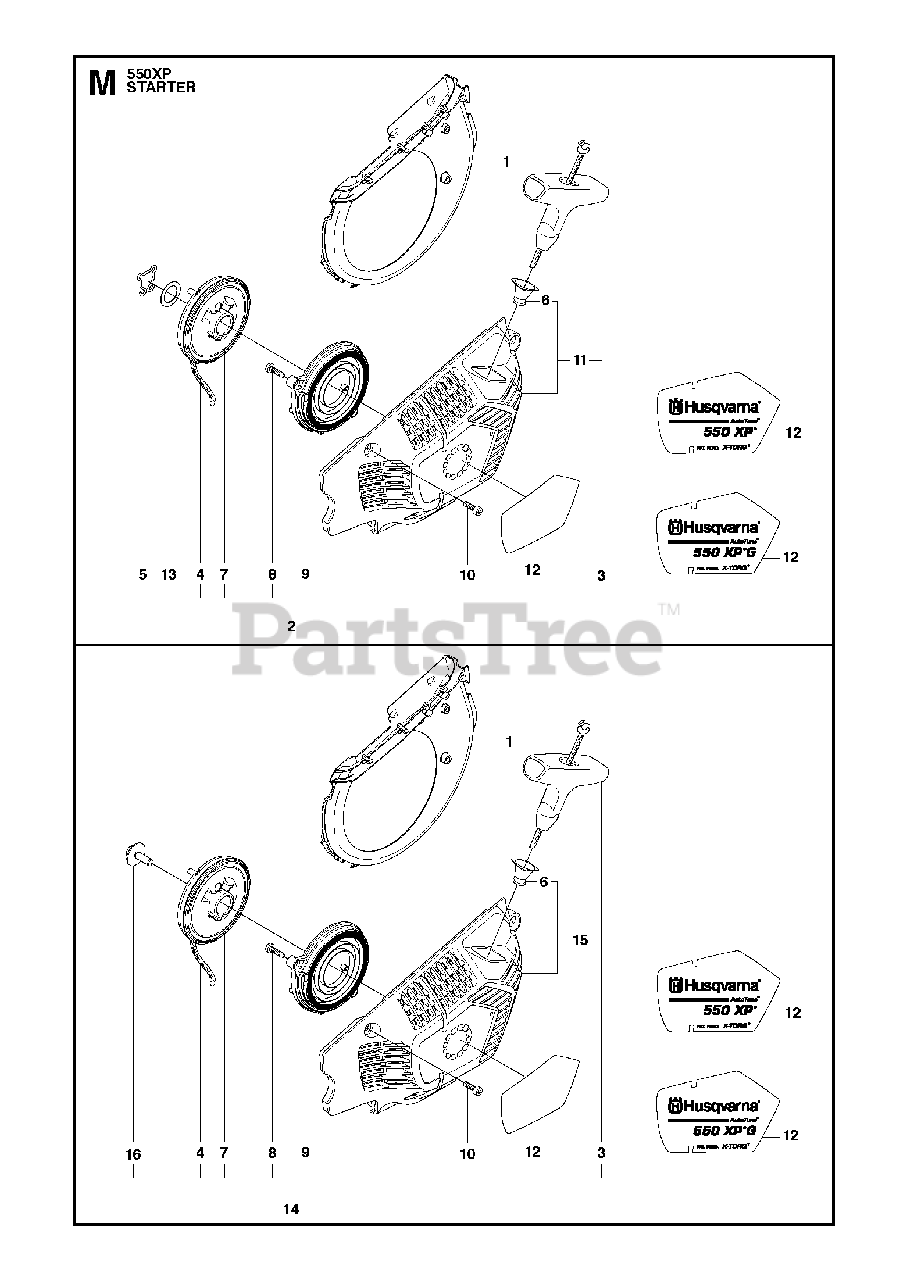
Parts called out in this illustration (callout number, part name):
1	COOLING AIR CONDUCTOR
2	STARTER ASSY
3	HANDLE
4	STARTER ROPE
5	CLIPS
6	SLEEVE
7	STARTER PULLEY ASSY
8	SCREW
9	SPRING CASSETTE ASSY
10	SCREW
11	STARTER HOUSING
12	LABEL
13	WASHER
14	STARTER ASSY
15	STARTER HOUSING
